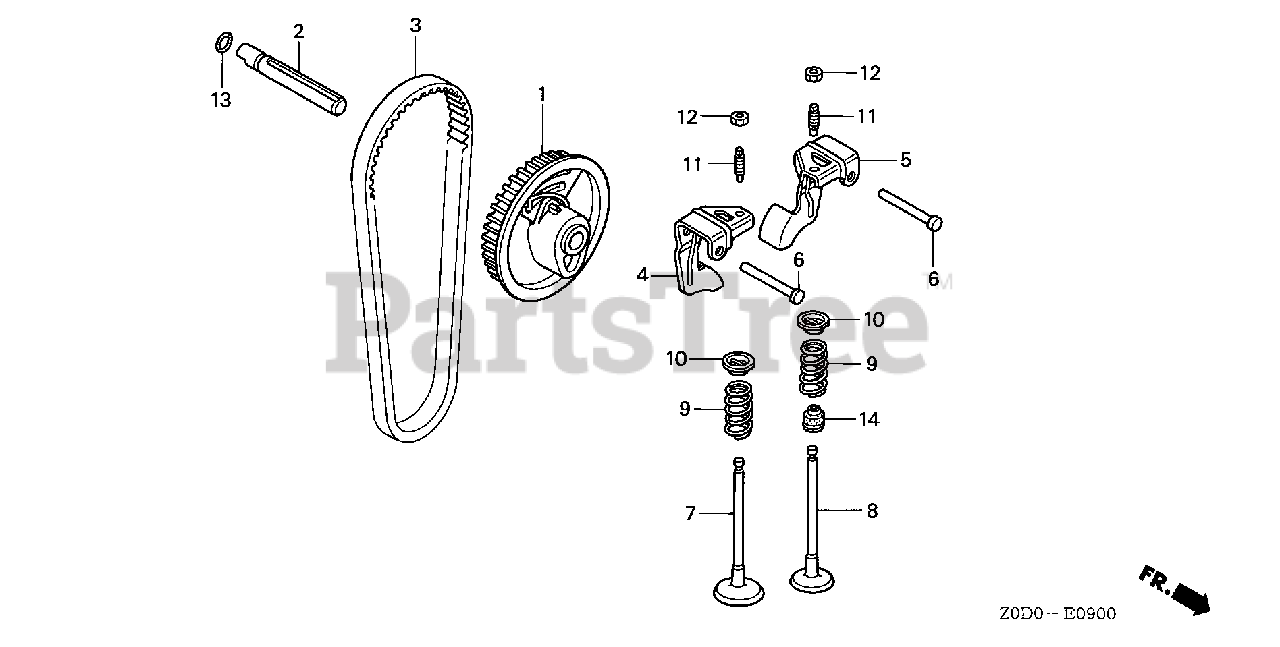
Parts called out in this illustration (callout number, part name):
1	PULLEY, CAMSHAFT
2	SHAFT, CAM PULLEY
3	BELT, TIMING (61YU7 G-200)
4	ARM, IN. VALVE ROCKER
5	ARM, EX. VALVE ROCKER
6	SHAFT, ROCKER ARM
7	VALVE, IN.
8	VALVE, EX.
9	SPRING, VALVE
10	RETAINER, VALVE SPRING
11	SCREW, TAPPET ADJ.
12	NUT, TAPPET ADJ.
13	O-RING (6.8X1.9)
14	SEAL, VALVE STEM
